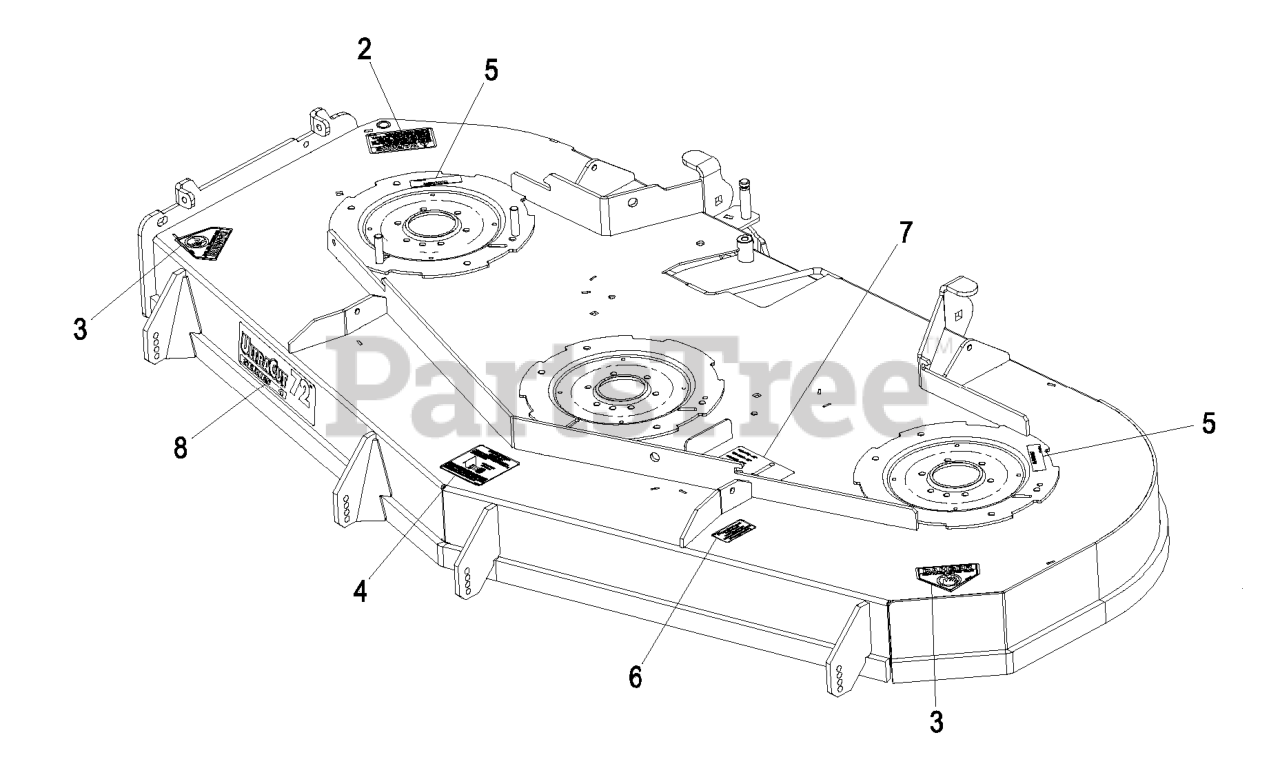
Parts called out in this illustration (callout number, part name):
2	DECAL-WARNING, DISCHARGE
3	DECAL-DANGER
4	DECAL,ANTISCALP
5	DECAL-COVER, MISSING
6	DECAL,BOLT TORQUE
7	DECAL,BELT ROUTING
8	DECAL,ULTRACUT 72 SERIES
